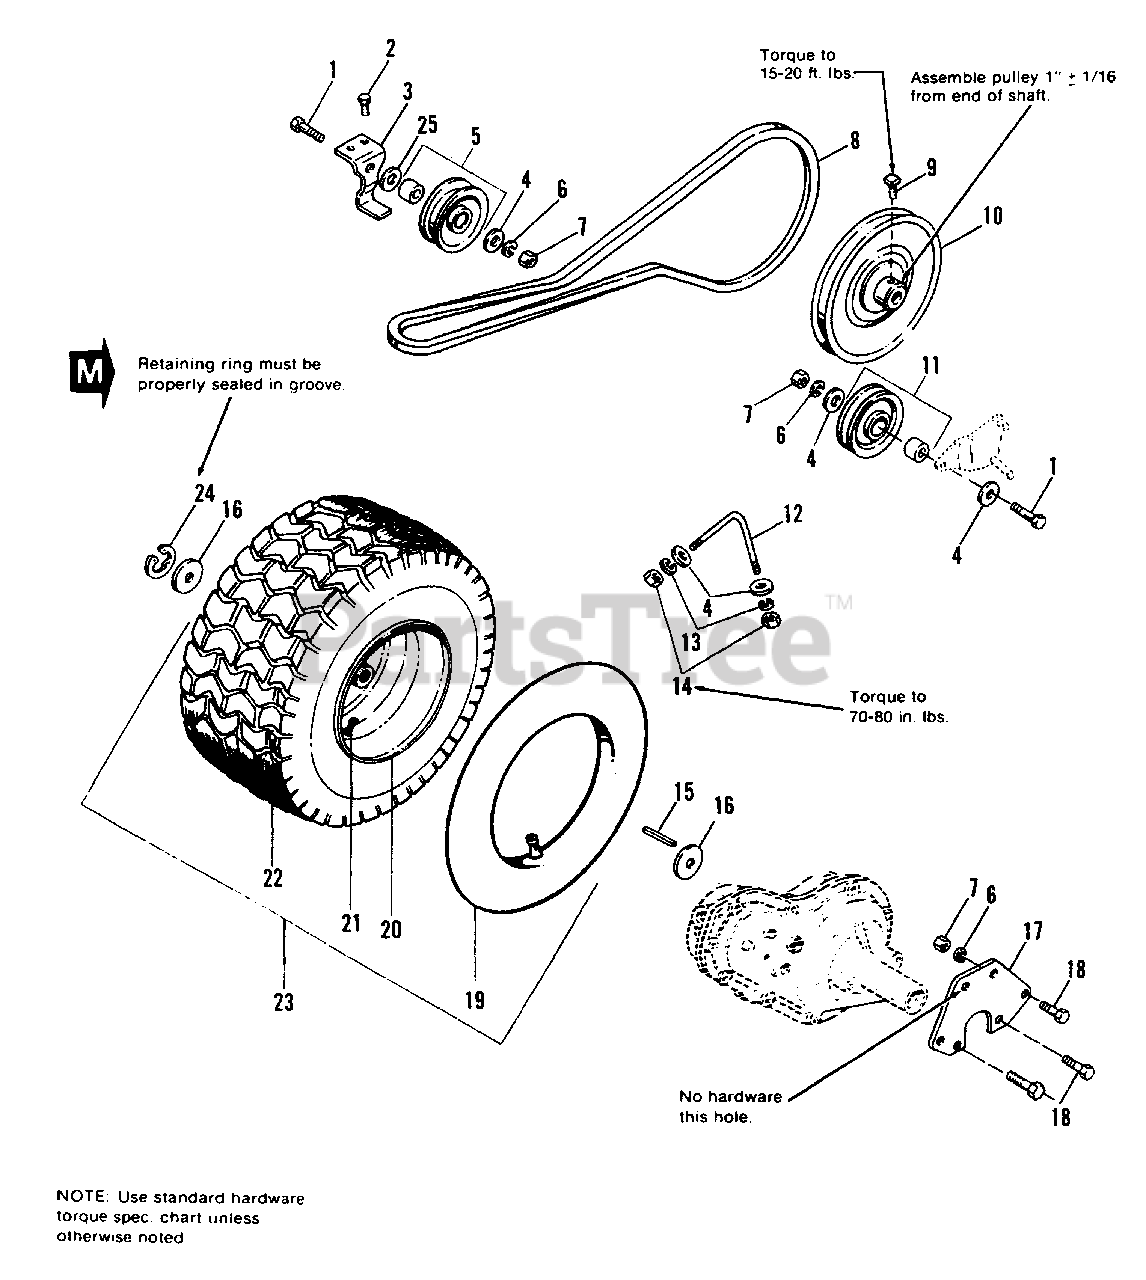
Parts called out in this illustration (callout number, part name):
1	CAPSCREW, Hex, 3/8-16 x 1-1/4
2	SCREW, Hex, Taptite, 1/4-20 x 3/8
3	BRACKET, Idler
4	WASHER, Plain, 5/16
5	PULLEY ASSY., Kit
6	LOCKWASHER, 3/8
7	NUT, Hex, Full, 3/8-16
8	V-BELT, (Drive)(Used on 6116 & 6118)
8	V-BELT (Drive)(Used on 6108 & 6111)
9	SETSCREW, 5/16-18 x 1/2
10	PULLEY ASSY., Transmission
11	PULLEY ASSY., Kit
12	BOLT, Axle
13	LOCKWASHER, 5/16
14	NUT, Hex, Full, 5/16-18
15	KEY, 1/4 x 1/4 x 2-1/4
17	SUPPORT, Bracket
18	CAPSCREW, Hex, Whizlock, 3/8-16 x 1
19	TUBE (Used on 6116 & 6118)
19	TUBE (Used on 6108 & 6111)
20	WHEEL ASSY.
21	VALVE STEM & CAP
22	TIRE, 20 x 10-10 Carlisle (6116 & 6118)
22	TIRE, Goodyear or Carlisle (Used on 6108 & 6111)
23	WHEEL & TIRE ASSY., 20 x 10-10 (Used on 6116 & 6118)
23	WHEEL & TIRE ASSY. (Used on 6108 & 6111)
24	E-RING Ext.
25	WASHER, Plain, 13/32
